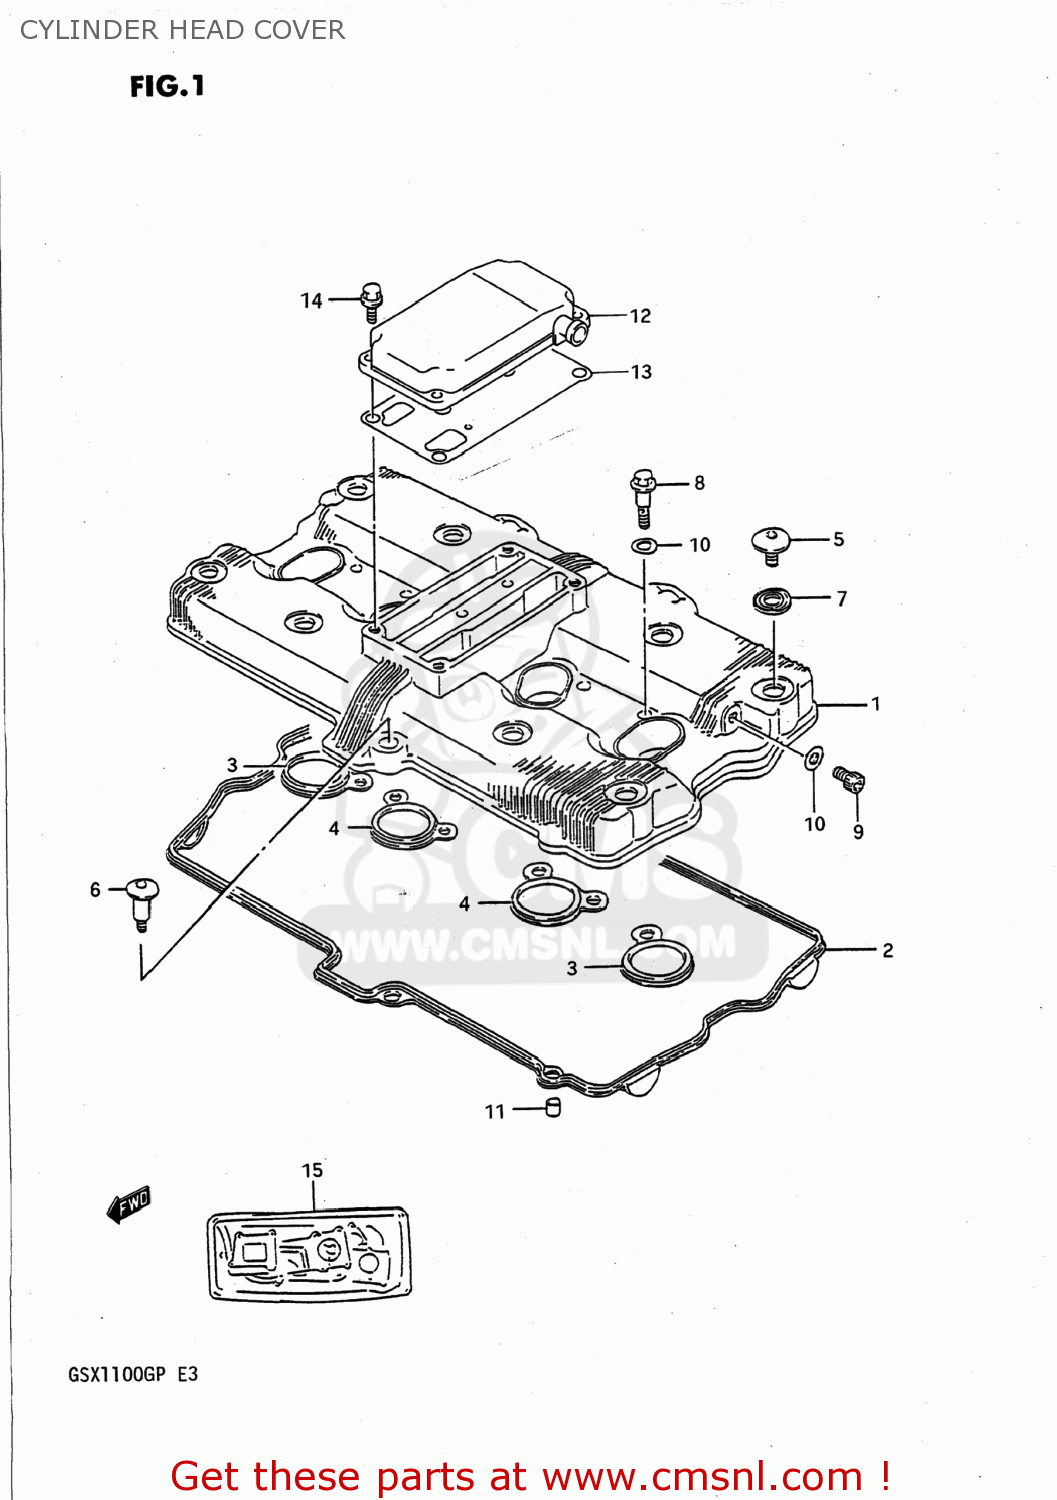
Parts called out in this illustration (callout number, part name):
1	COVER,CYLINDER HEAD
2	GASKET,CYLINDER HEAD COVER (NAS)
3	GASKET,HEAD COVER NO.2 (NAS)
4	GASKET,HEAD COVER NO.3 (NAS)
5	BOLT(7X17.5)
6	BOLT(7X31)
7	WASHER(10.6X25.5X2.3)
8	BOLT,UNION 8X35
9	PLUG, HEAD COVER
10	GASKET 8.2X14X1 (NAS)
11	PIN
12	COVER,BREATHER
13	GASKET,BREATHER COVER ( (NAS)
14	BOLT
15	GASKET SET (NAS)
